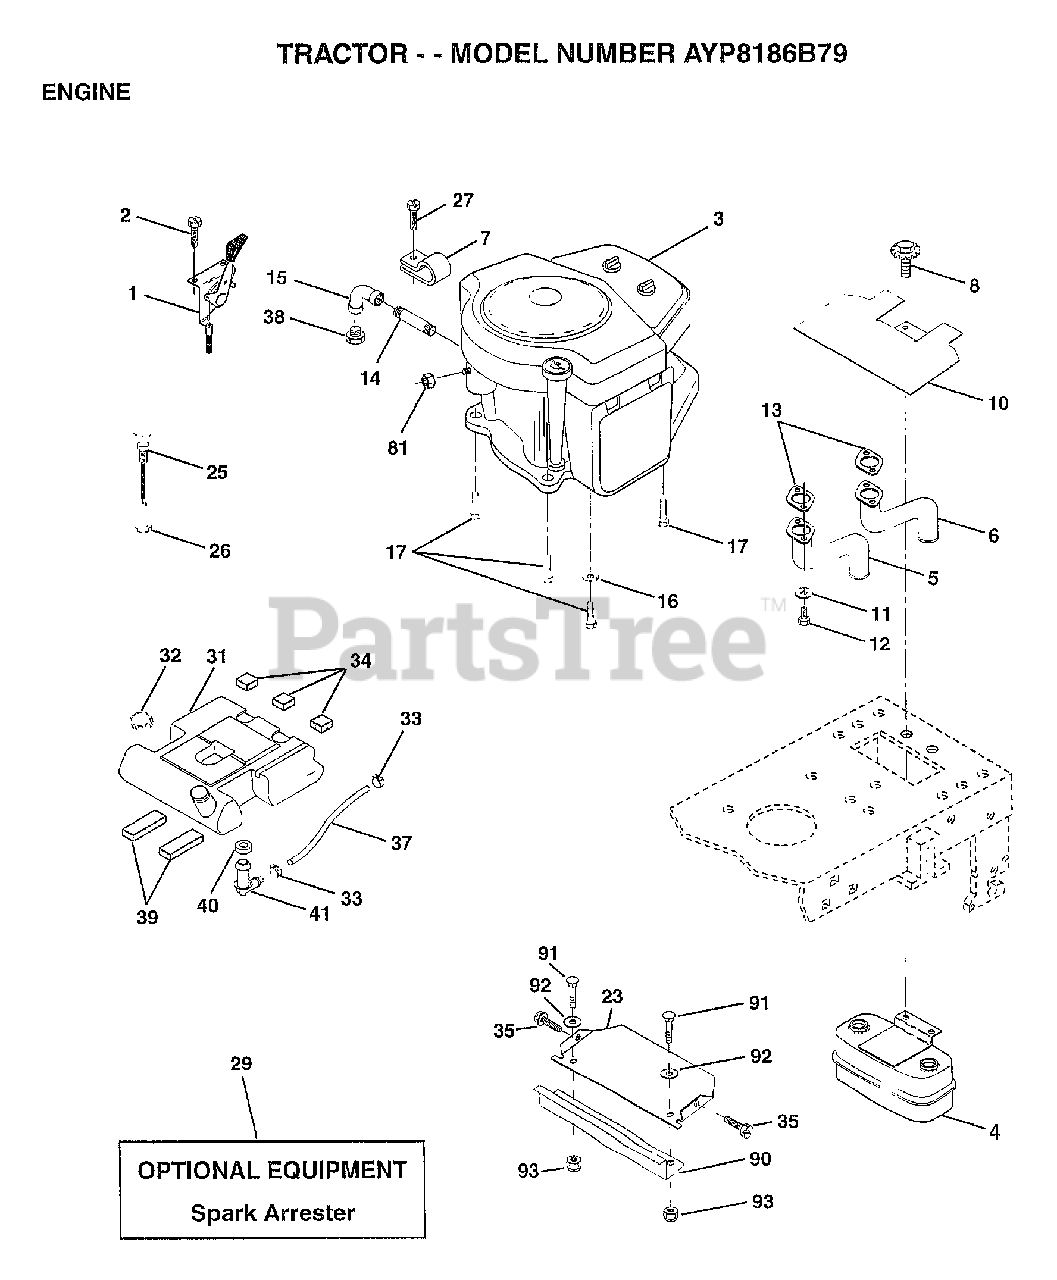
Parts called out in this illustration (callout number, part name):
1	CONTROL THRT 35.5
2	SCREW LT
3	ENGINE, BRIGGS
4	MUFFLER.TW.LOTONE
5	EXHAUST.B&S.18.RH
6	EXHAUST.B&S.18.LH
7	CLAMP.TUBE.DBL.EN
8	BOLT.5/16-18.UNC
10	SHIELD.HEAT.
11	LOCKWASHER
13	GASKET MUFFLER
14	PIPE NIPPLE LT
15	ELBOW
16	LOCKWASHER
17	SCREW LT
23	SHIELD-HEAT
25	CONTROL.CHOKE.37
26	"NUT,KEPS 3/8-24IM"
27	"SCREW-TT,10-32 FL"
31	TANK FUEL REAR
32	CAP ASM FUEL
33	HOSE CLAMP
34	PAD-SPACER LT
35	SCREW
37	FUEL LINE T
39	PAD IDLER TI
40	BUSHING OUTLET T
41	STEM.TANK.FUEL
81	NUT
90	GUARD-DEBRIS
91	BOLT HXHD FIN
92	WASHER
